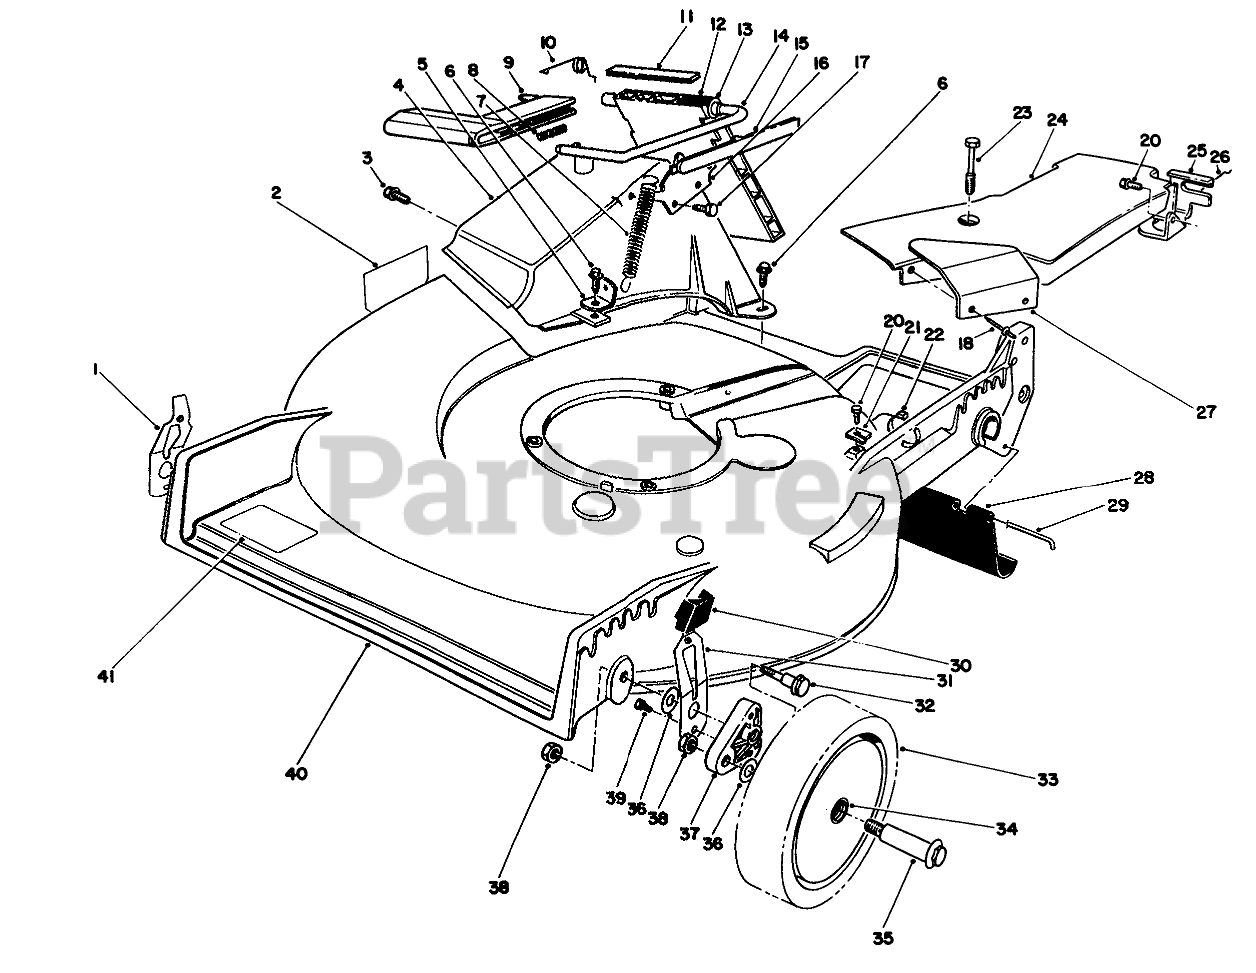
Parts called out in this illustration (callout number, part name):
1	RH SPRING ARM ASSEMBLY
2	DECAL-DANGER
3	SCREW AND WASHER ASM
4	DISCHARGE TUNNEL
5	Bracket-Spring
6	SCREW-HWH
7	SPRING-DOOR
8	Spring
9	Handle-Door
10	RETAINER-DOOR
11	Cover-Door
12	Door-Discharge
13	BUSHING-NYLON
14	Rod-Door
15	Cover-Handle
16	DOOR LATCH PLATE
17	SCREW-PLASTITE
18	RIVET-HEAD, FLAT
20	SCREW-HWHTF
21	CLAMP-CABLE
22	TIE-CABLE
23	SCREW-HHFTF
24	Belt Cover Assembly (Incl. Ref. #18 & 27)
25	Bracket-Adj. Trac
26	RETAINER-CABLE
27	HEAT SHIELD
28	SHIELD-TRAILING
29	ROD-SHIELD
30	KNOB-ARM
31	LH SPRING ARM ASSEMBLY
32	SCREW-SHOULDER
33	Wheel & Tire Ass-y (Incl. Ref. #34)
34	BUSHING
35	WHEEL BOLT
36	WASHER
37	ARM-PIVOT, FRONT
38	Nut
39	SCREW-HWH
40	Housing Assembly (Incl. Ref. #2 & 6)
41	DECAL
